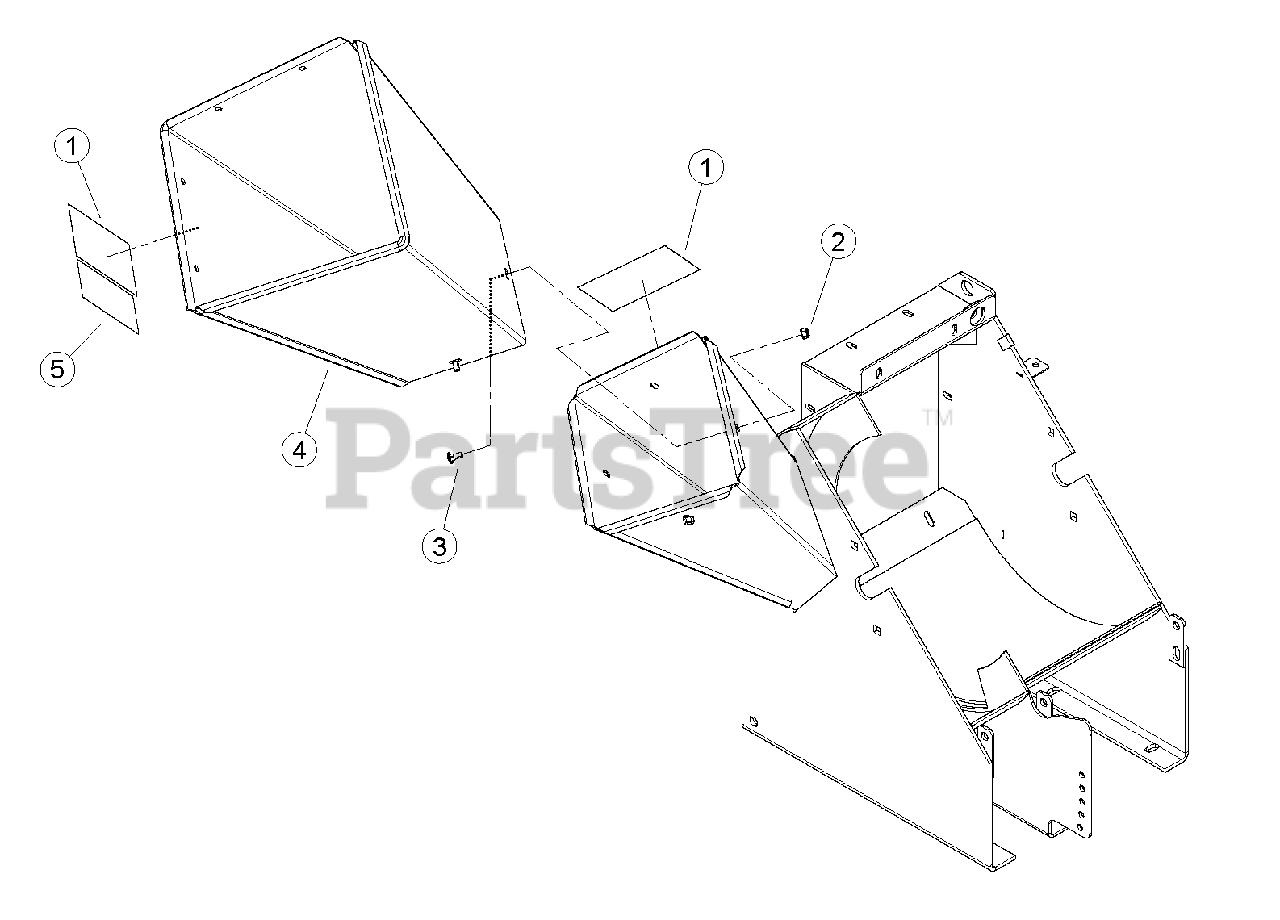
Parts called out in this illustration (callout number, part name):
1	DECAL, BLADE DANGER ISO
2	BOLT, 5/16 X 3/4 GR5 NC ZP CRG
3	NUT, 5/16-18 NYLOCK-FLANGE
4	ASSEMBLY, COMM CHUTE EXTENSION W/ DECAL
5	DECAL, MUTILINGUAL MANUAL
